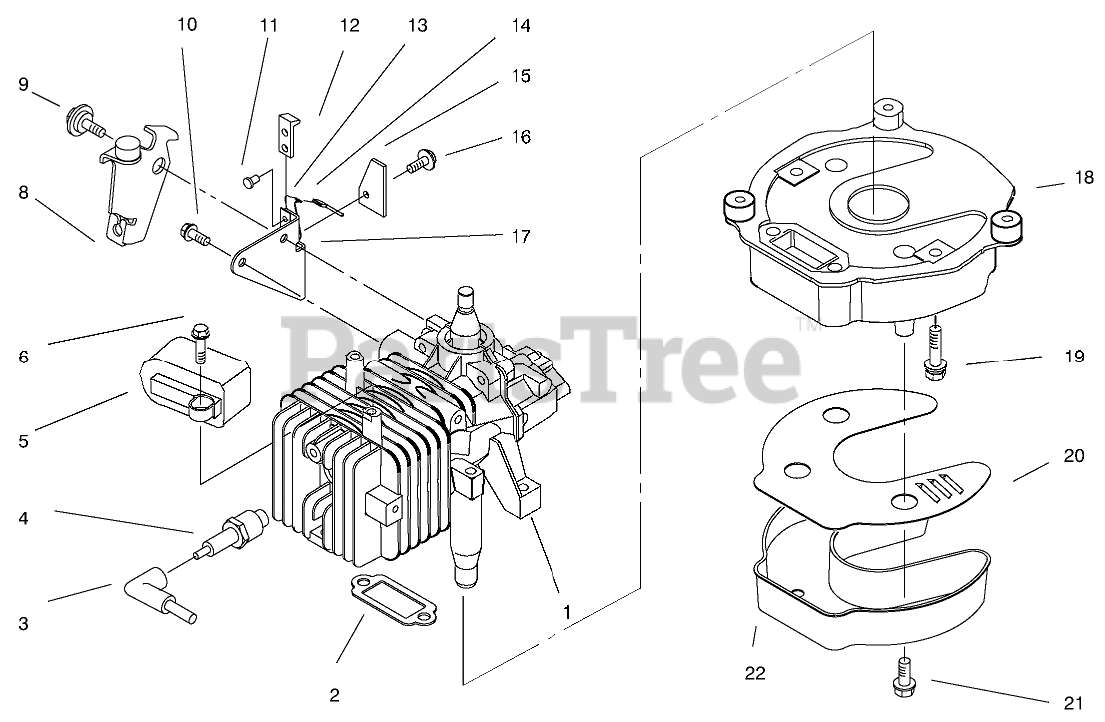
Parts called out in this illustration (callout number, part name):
1	Short Block (Incl. Ref. #2, Ref. #9 pg. 8)
2	GASKET-EXH. VF
3	CD Ignition
4	SPARK PLUG
5	CD Ignition (Incl. Ref. #3)
6	SCREW
8	PLATE-BRAKE
9	SCREW-SHOULDER
10	SCREW
11	RIVET-PLASTIC
12	STRAP-INSULATION
13	STRAP-GROUND
14	ELECTRICAL LEAD ASM
15	STOP-GROUND STRAP
16	SCREW
18	PLATE-MUFFLER V
19	SCREW V
20	BAFFLE-MUFFLER
21	SCREW
22	Cover-Muffler
